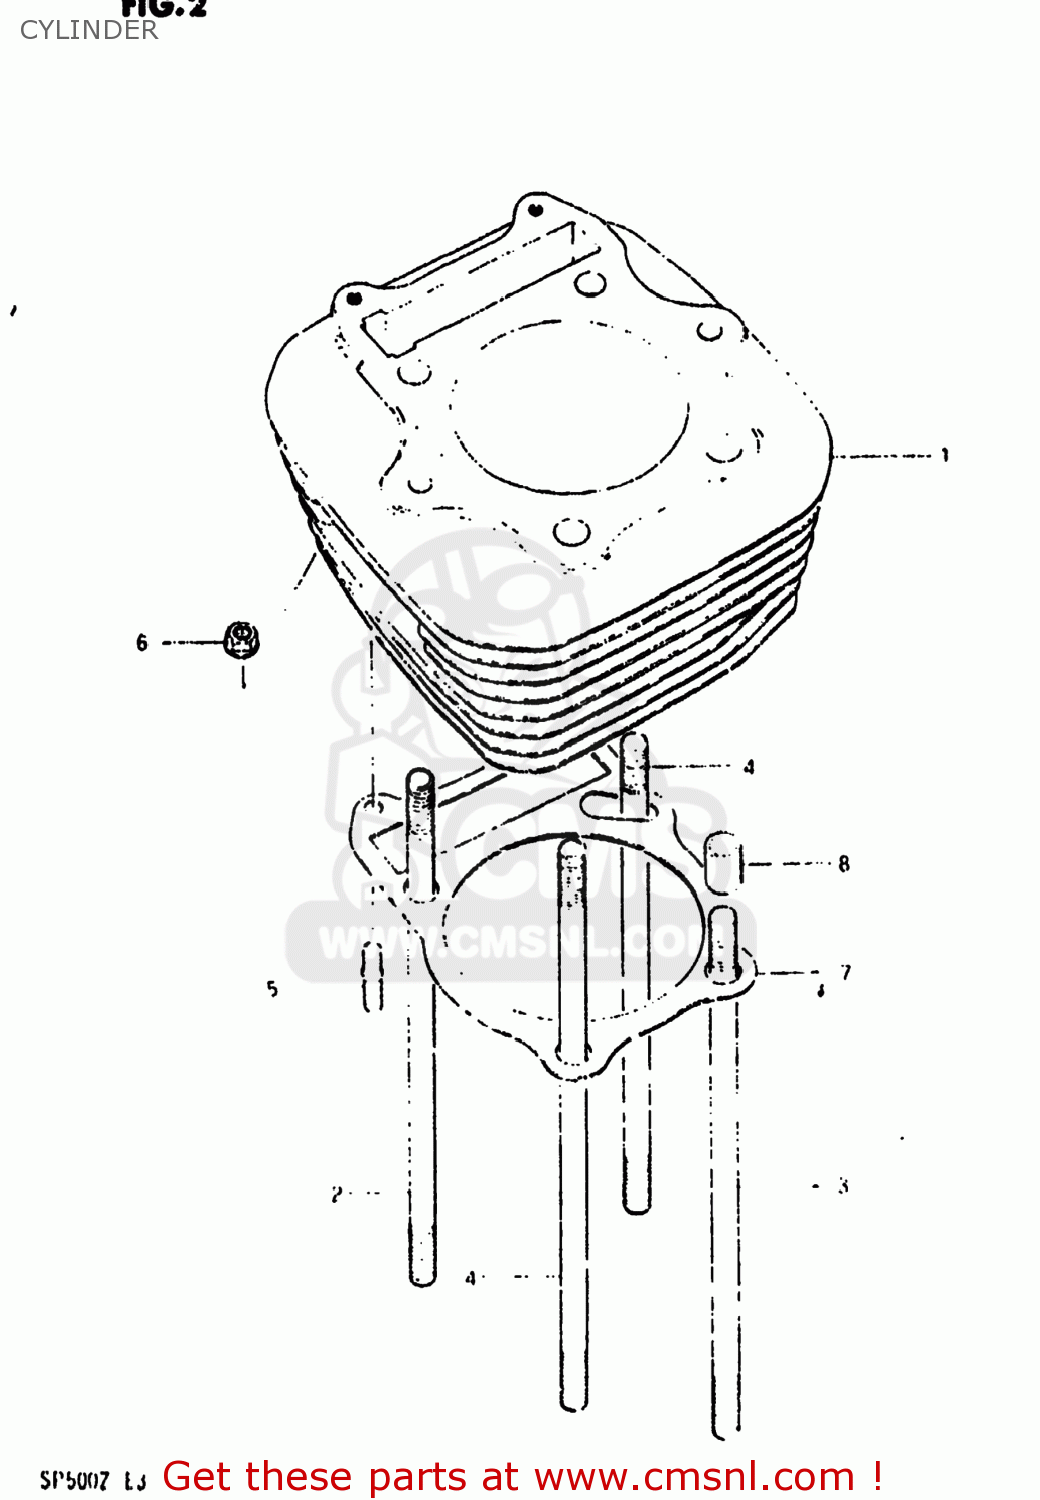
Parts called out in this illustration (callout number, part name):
1	CYLINDER
2	STUD
3	STUD
4	BOLT,STUD
5	STUD 6X25
6	NUT
7	GASKET,CYLINDER (NAS)
8	PIN
